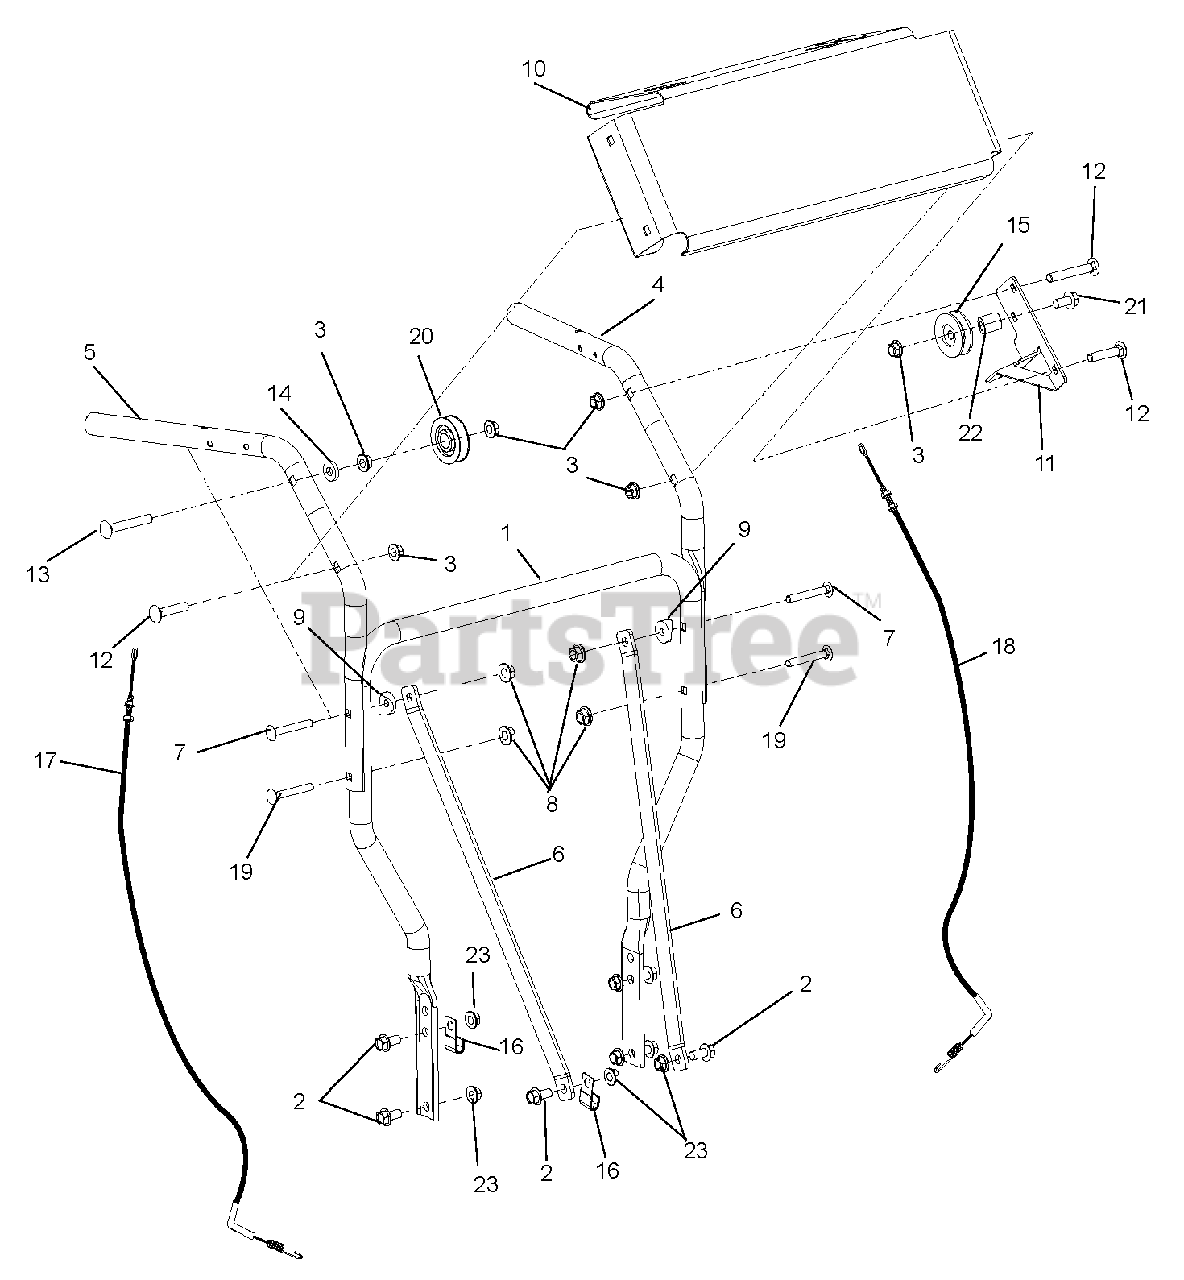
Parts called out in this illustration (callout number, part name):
1	Handlebar, Lower
2	Bolt, Screw Hex Flanged Whiz Lock Head .38-16 x .75
3	Nut, Locking Top Flange .38-16
4	Handlebar, Upper Left Hand
5	Handlebar, Upper Right Hand
6	Bracket, Handlebar Brace
7	Bolt, Round Head Square Neck .31-18 x 2.25
8	Nut, Nyloc Flange .31-18
9	Spacer, Handlebar
10	Dash, WAW
11	Mount, PTO Cable
12	Bolt, Round Head Square Neck .38-16 x 1.75
13	Bolt, Round Head Square Neck .38-16 x 2.50
14	Washer, Flat Steel .406 x 1.0 x .18
15	Idle, 3L Front Side .38 x 1.875
17	Cable, P-Brake
18	Cable, PTO
19	Bolt, Round Head Square Neck .312-18 x 1.75
20	Pulley, Cable
21	Bolt, Hex .38-16 x 2.50
22	Spacer, .437 x 1.00 x 1.23
23	Nut, Locking Center Flange .38-16
